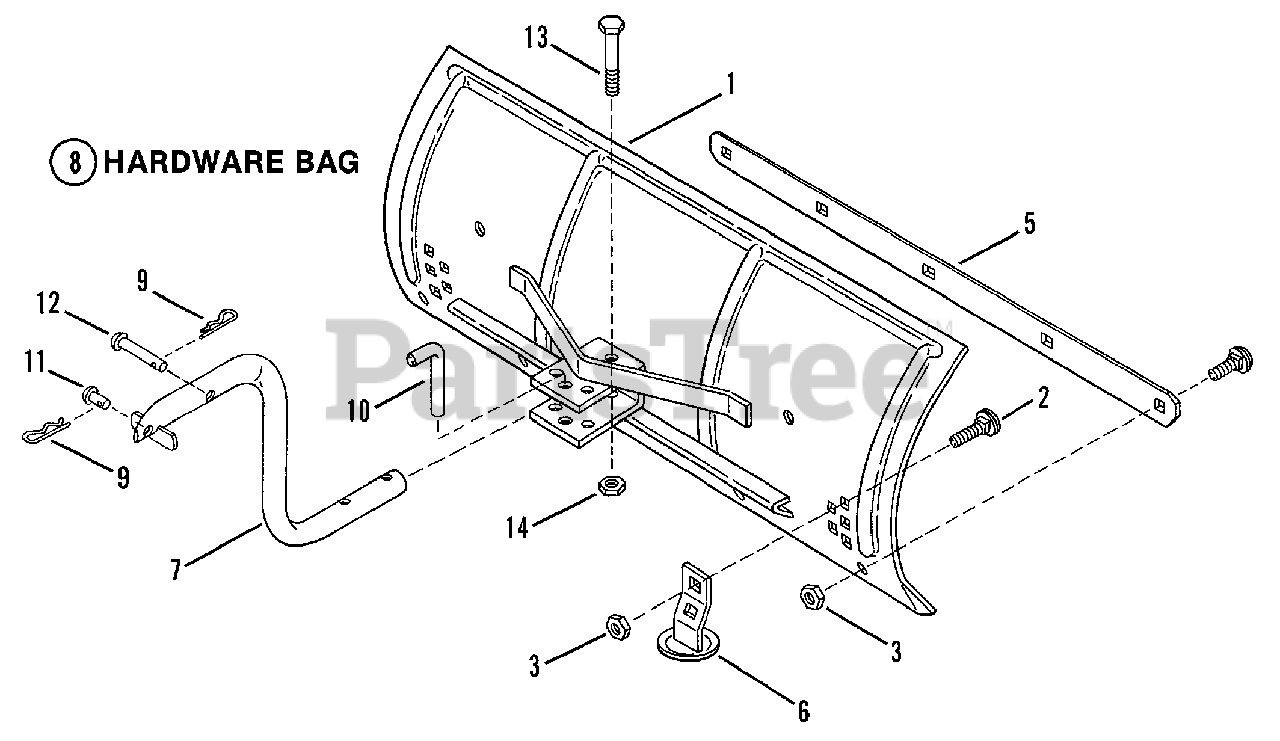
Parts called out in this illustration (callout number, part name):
1	BLADE STRUCTURE
2	BOLT, 3/8-16 x 1" Square Neck Carriage, Gr. 2
3	NUT, 3/8-16 Hex Center Lock
4	BOLT, 3/8-16 x 3/4" Square Neck Carriage, Gr. 2
5	SCRAPER
6	SLIDE
7	(NLA) ASSEMBLY, Tongue
9	HAIRPIN
10	PIN, 3/8 x 3-1/4" Hitch
11	PIN, 5/16 x 3/4" Short
12	PIN, 5/16 x 2-1/2" Long
13	SCREW, 1/2-20 x 2-3/4" Hex Head Cap
14	NUT, 1/2-20 Hex Center Lock
